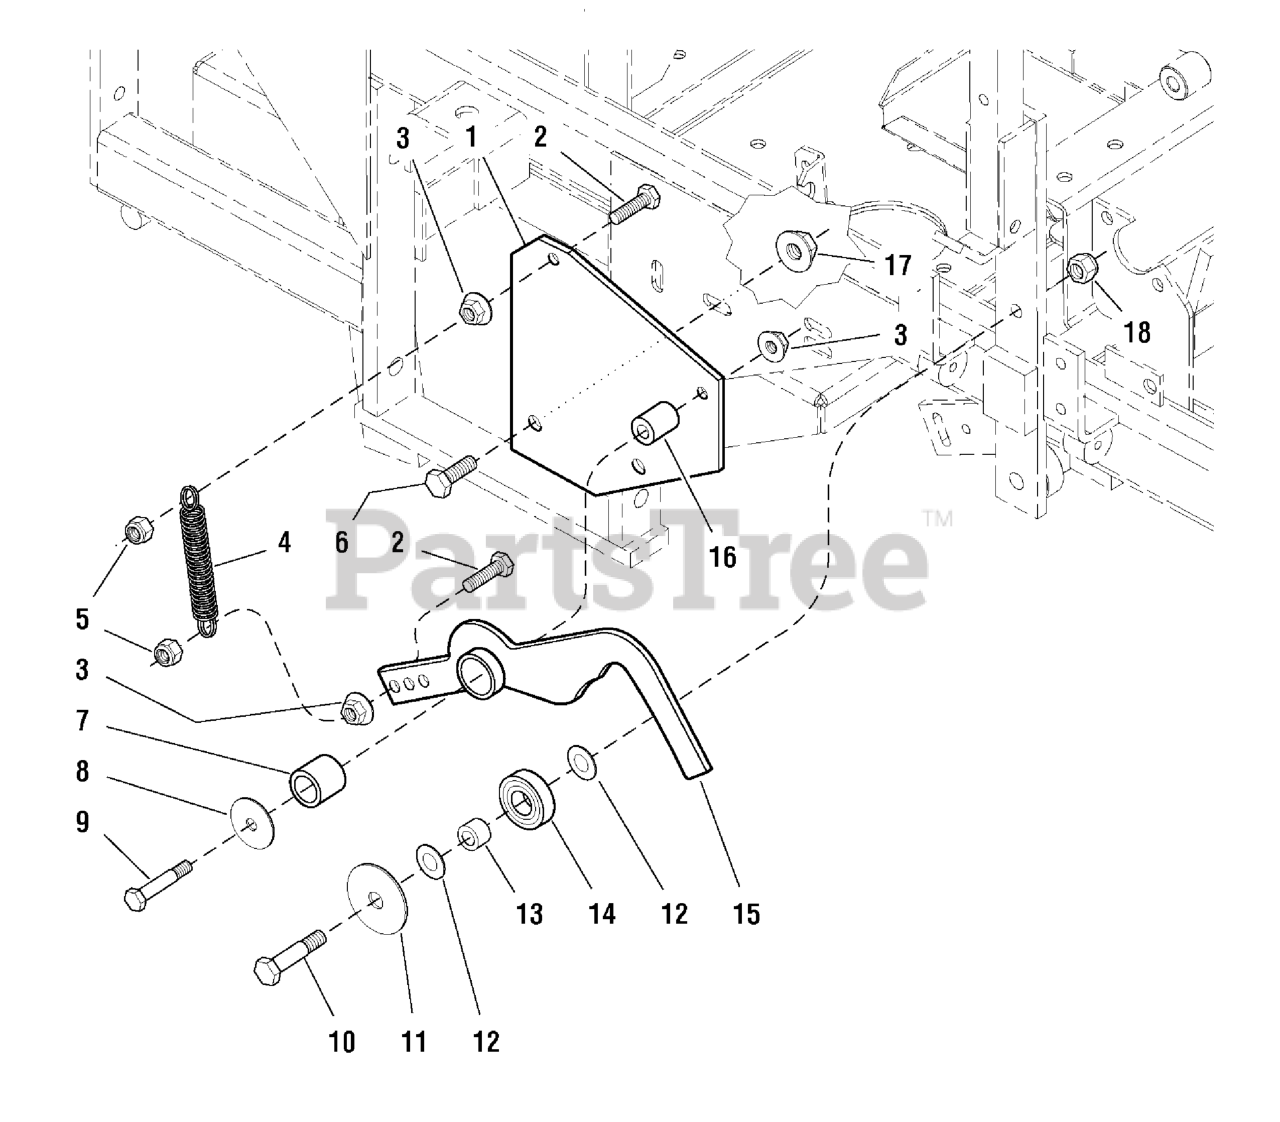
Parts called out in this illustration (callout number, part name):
1	NEUTRAL RETURN MOUNT PLATE
2	BOLT, 5/16-18 X 1-1/4 GD5 TFL, CZ
3	NUT, 5/16-18 HEX SERRATED FLANGE (LARGE)
4	SPRING, Extension
5	NUT, 5/16-18 Hex Nylon Lock
6	BOLT, 3/8-16 X 3/4" GD5 CZ
7	BUSHING, Brass
8	WASHER, 5/16" Fender
9	BOLT, 5/16-18 x 1-3/4
10	BOLT, 3/8-16 X 1-3/4" GD5 CZ
11	WASHER, 3/8 x 2
12	WASHER, 3/8 SAE
13	INSERT, Bearing
14	BEARING, BALL 11/16X1-9/16X15/32
15	NEUTRAL RETURN LEVER
16	SPACER, .32 x .75 x 1.06
17	NUT, 3/8-16 Hex Serrated Flange
18	NUT, 3/8-16 HEX NYLON LOCK
